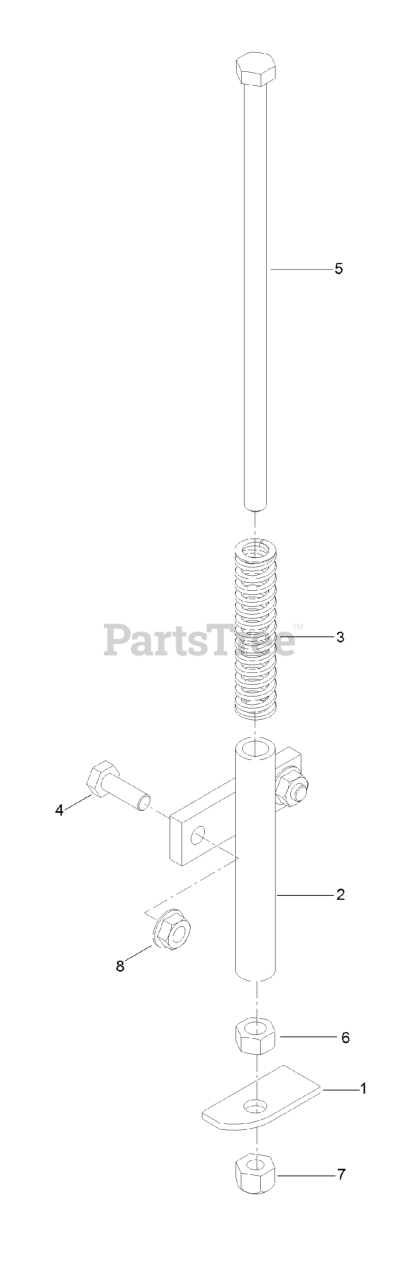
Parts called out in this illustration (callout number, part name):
1	Plate-Switch
2	MOUNT-SPRING, SEAT
3	SPRING-SWITCH, SEAT
4	SCREW-HH
5	SCREW-HH
6	NUT-HEX
7	NUT-LOCK, NI
